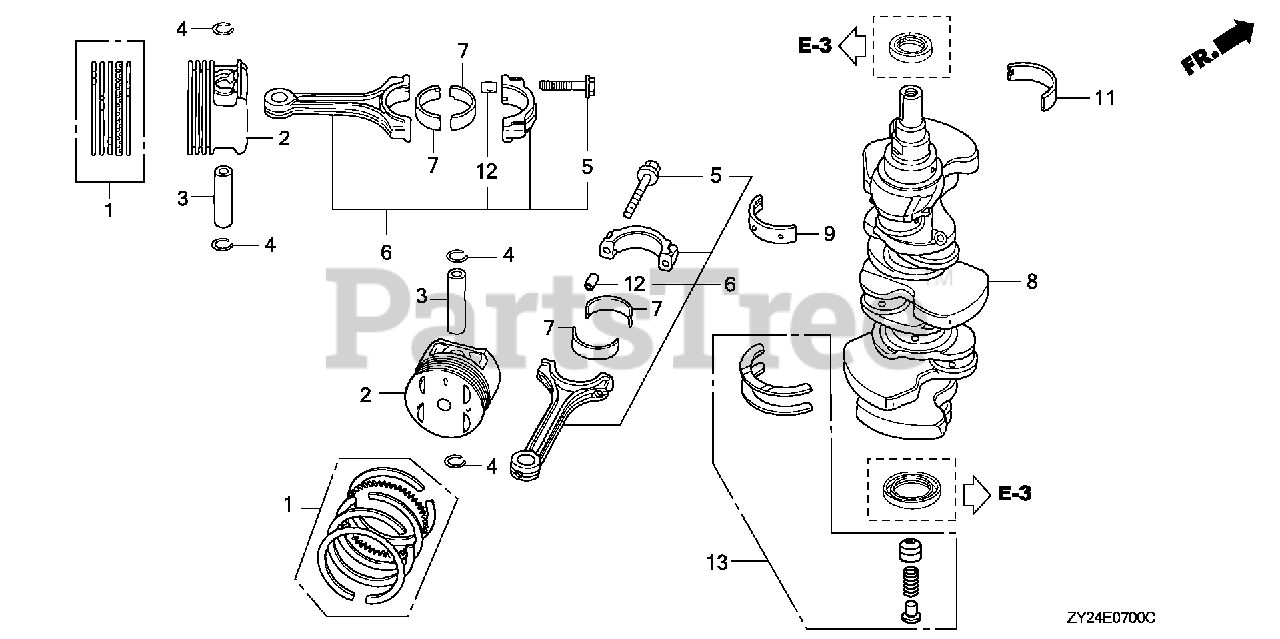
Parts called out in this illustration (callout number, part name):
1	RING SET, PISTON (STD)
1	RING SET, PISTON (0.25)
2	PISTON
2	PISTON (0.25)
3	PIN, PISTON
4	CLIP, PISTON PIN
5	BOLT, CONNECTING ROD
6	ROD, CONNECTING
7	BEARING A, CONNECTING ROD (BLACK) (TAIHO)
7	BEARING B, CONNECTING ROD (BROWN) (TAIHO)
7	BEARING C, CONNECTING ROD (GREEN) (TAIHO)
7	BEARING D, CONNECTING ROD (YELLOW) (TAIHO)
7	BEARING E, CONNECTING ROD (PINK) (TAIHO)
8	CRANKSHAFT
9	BEARING A, MAIN (UPPER) (BLACK) (DAIDO)
9	BEARING B, MAIN (UPPER) (BROWN) (DAIDO)
9	BEARING C, MAIN (UPPER) (GREEN) (DAIDO)
9	BEARING D, MAIN (UPPER) (YELLOW) (DAIDO)
9	BEARING E, MAIN (UPPER) (PINK) (DAIDO)
9	BEARING F, MAIN (UPPER) (RED) (DAIDO)
11	BEARING A, MAIN (LOWER) (BLACK) (DAIDO)
11	BEARING B, MAIN (LOWER) (BROWN) (DAIDO)
11	BEARING C, MAIN (LOWER) (GREEN) (DAIDO)
11	BEARING D, MAIN (LOWER) (YELLOW) (DAIDO)
11	BEARING E, MAIN (LOWER) (PINK) (DAIDO)
11	BEARING F, MAIN (LOWER) (RED) (DAIDO)
12	PIN, DOWEL (10X12)
13	WASHER KIT, THRUST (175/200/225)
